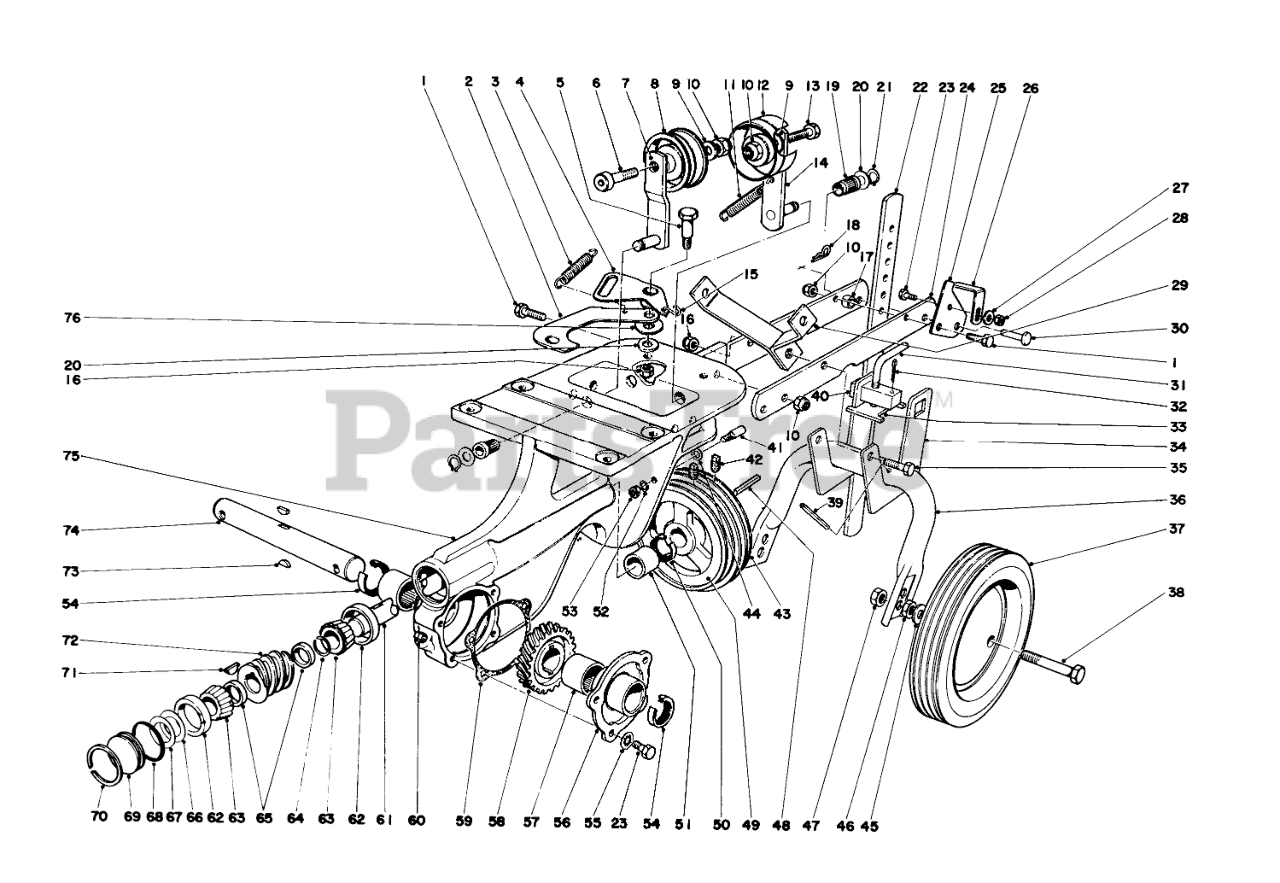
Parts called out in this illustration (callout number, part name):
1	SCREW-HH
2	Rev. Link
3	Spring
4	Bellcrank
5	SCREW-SHOULDER, HH
6	Socket Hd. Capscrew
7	IdlerArm
8	PULLEY IDLER
9	WASHER-FLAT
10	NUT-LOCK, CONE
11	Spring
12	IDLER PULLEY
13	SCREW-HH
14	Idler
15	S Hook
16	NUT-LOCK, CONE
17	Spacer
18	PIN-COTTER, HAIR
19	IDLER BRG
20	WASHER-PLAIN
21	RING-RETAINING, EXT
22	DEPTH GAGE
23	SCREW-HH
24	Drawbar
25	Hinge Latch
26	Drag Bar Latch
27	WASHER-FLAT
28	NUT-LOCK, CONE
29	Handle Support
30	TINE PIN
31	Handle Jack
32	PIN-COTTER
33	Jack Plate
34	Axle Saddle
35	SCREW-HH
36	Axle Yoke
37	Wheel
38	Capscrew
39	Roll Pin
40	Jack Nut
41	Belt Guide
42	SCREW-SET, HSH
43	Pulley
44	WASHER-FLAT
45	WASHER-FLAT
46	NUT-JAM
47	1/2-13 CONELOCK NUT
48	KEY-SQUARE
49	Pulley
50	SEAL-OIL
51	BUSHING
52	WASHER-LOCK/EXT
53	NUT-JAM
54	SEAL-OIL
55	WASHER-LOCK
56	Cover
57	Bearing
58	WORM WHEEL
59	GASKET
60	PLUG-PIPE, SQH
61	WORM SHAFT
62	BEARING-ROLLER, CUP
63	BEARING-CONE
64	RETAINER RING
65	SPACER
68	O-RING
70	INTRNL RETAINING RING
71	KEY-WOODRUFF
72	WORM GEAR
73	KEY-WOODRUFF
74	WORM WHEEL SHAFT
75	Chassis
76	WASHER-FLAT
